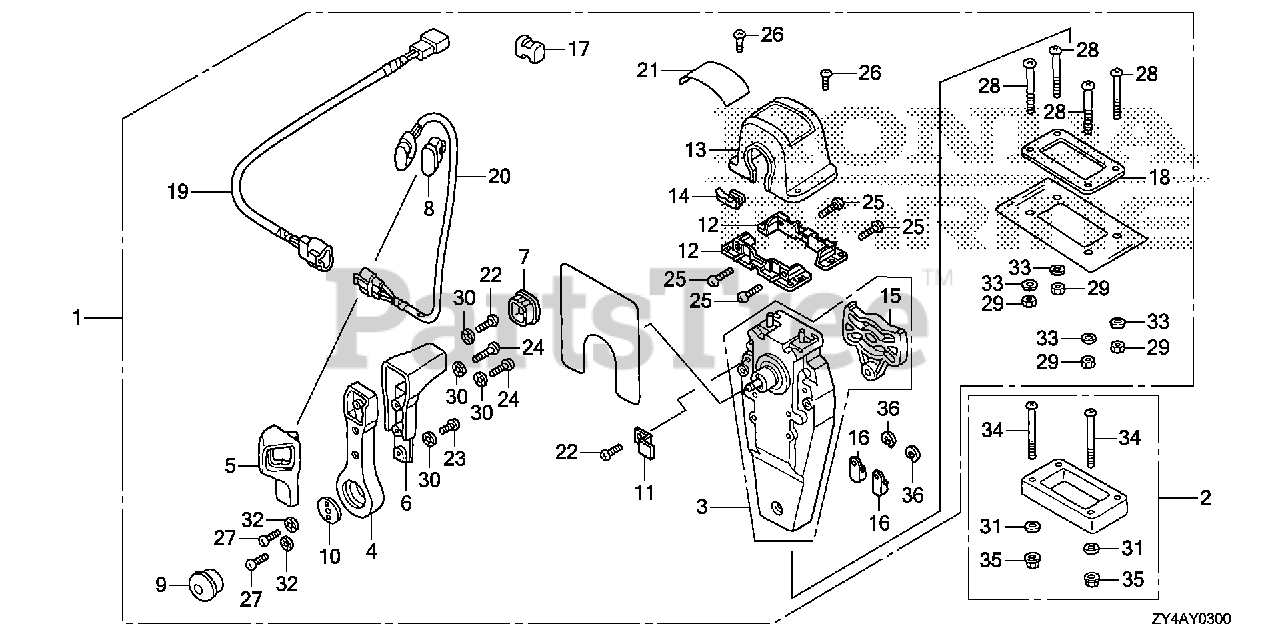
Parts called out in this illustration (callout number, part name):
1	BOX KIT, REMOTE CONTROL (TOP MOUNT SINGLE)(R)
2	SPACER KIT, REMOTE CONTROL BOX (TOP MOUNT SINGLE)
3	HOUSING ASSY., L. (INNER) (TOP MOUNT)
4	HANDLE, REMOTE CONTROL
5	COVER, L. GRIP
6	GRIP, REMOTE CONTROL HANDLE
7	CAP, GRIP
8	CAP, SWITCH
9	BUTTON, THROTTLE
10	PLATE, HANDLE
11	PLATE, CABLE CLAMP
12	BRACKET, REMOTE CONTROL HOUSING
13	HOUSING, REMOTE CONTROL BOX
14	HOUSING, LEAD
15	PLATE, DWELL
16	TERMINAL, CABLE
17	SPACER, CABLE CLAMP
18	GASKET, SINGLE
19	SUB-HARNESS ASSY., POWER TRIM-TILT (A)
20	SWITCH ASSY., POWER TRIM-TILT (A)
21	MARK, REMOTE CONTROL (SINGLE)
22	SCREW, PAN (5X16)
23	SCREW, PAN (5X10)
24	SCREW, PAN (5X20)
25	SCREW, PAN (5X18)
26	SCREW, PAN (4X10)
27	SCREW, PAN (6X18)
28	SCREW, PAN (5X40)
29	NUT, HEX. (5MM)
30	WASHER, LOCK (5MM)
31	WASHER, PLAIN (5MM)
32	WASHER, LOCK (6MM)
33	WASHER, PLAIN (5MM)
34	SCREW, PAN (5X65)
35	NUT, HEX. (5MM)
36	E-RING (6MM)
